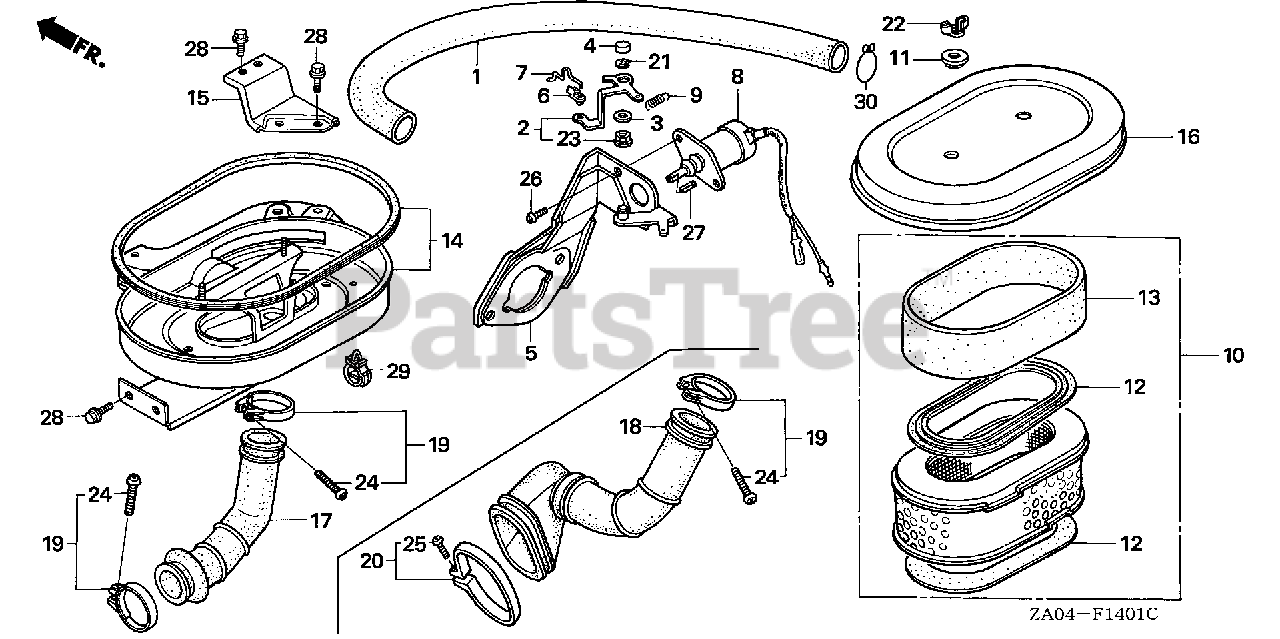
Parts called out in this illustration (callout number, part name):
10	ELEMENT, AIR CLEANER
11	WASHER, AIR CLEANER
13	FILTER (OUTER)
14	HOUSING, AIR CLEANER
15	STAY B, AIR CLEANER
16	COVER, AIR CLEANER *NH116M* (URBAN SILVER METALLIC)
17	TUBE, AIR CLEANER CONNECTING (NOT AVAILABLE)
19	BAND, CONNECTING TUBE
22	NUT, AIR CLEANER COVER (DACRO COATING)
24	SCREW, PAN (4X16)
28	BOLT, FLANGE (6X10)
